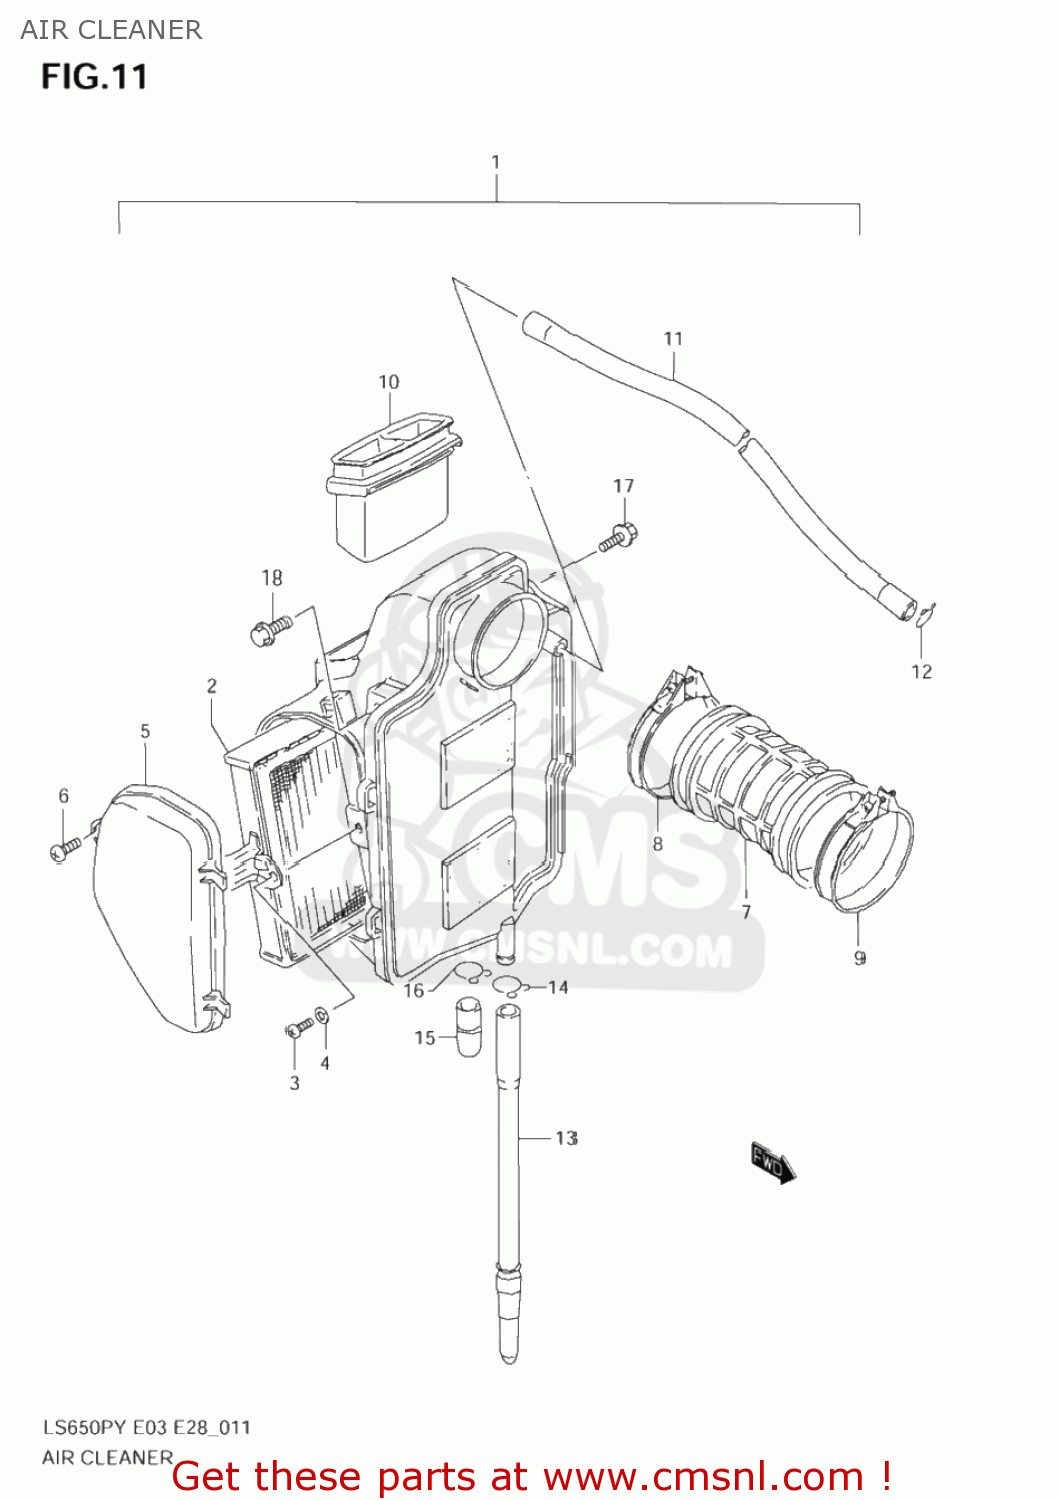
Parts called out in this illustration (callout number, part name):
1	CLEANER ASSY,AIR
2	FILTER ASSY,AIR
3	SCREW
4	WASHER,LOCK
5	CAP,AIR CLEANER
6	SCREW 5X12
7	TUBE,AIR CLEANER OUTLET
8	CLAMP
9	CLAMP
10	TUBE,INLET
11	HOSE(11X15X600)
12	CLIP
13	TUBE,DRAIN
14	CLIP
15	PLUG
16	CLIP
17	BOLT(6X16)
18	BOLT
